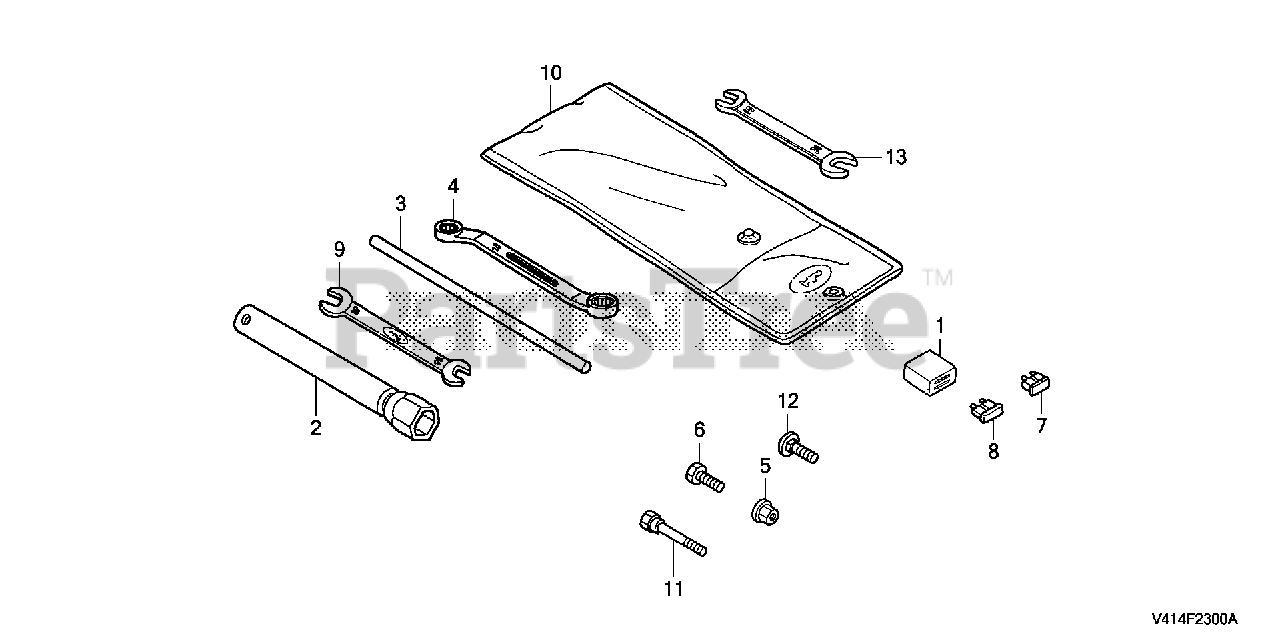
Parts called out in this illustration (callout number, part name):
2	WRENCH, SPARK PLUG (NOT AVAILABLE)
3	HANDLE, BOX WRENCH (NOT AVAILABLE)
5	NUT, SELF-LOCK (6MM)
6	BOLT, SPECIAL (6X18)
7	FUSE, BLADE (5A)
7	FUSE, MINI (5A)
9	WRENCH (14X17) (OPEN END)
10	BAG, TOOL
12	BOLT, CARRIAGE (6X18)
13	WRENCH (10X12) (OPEN END)
